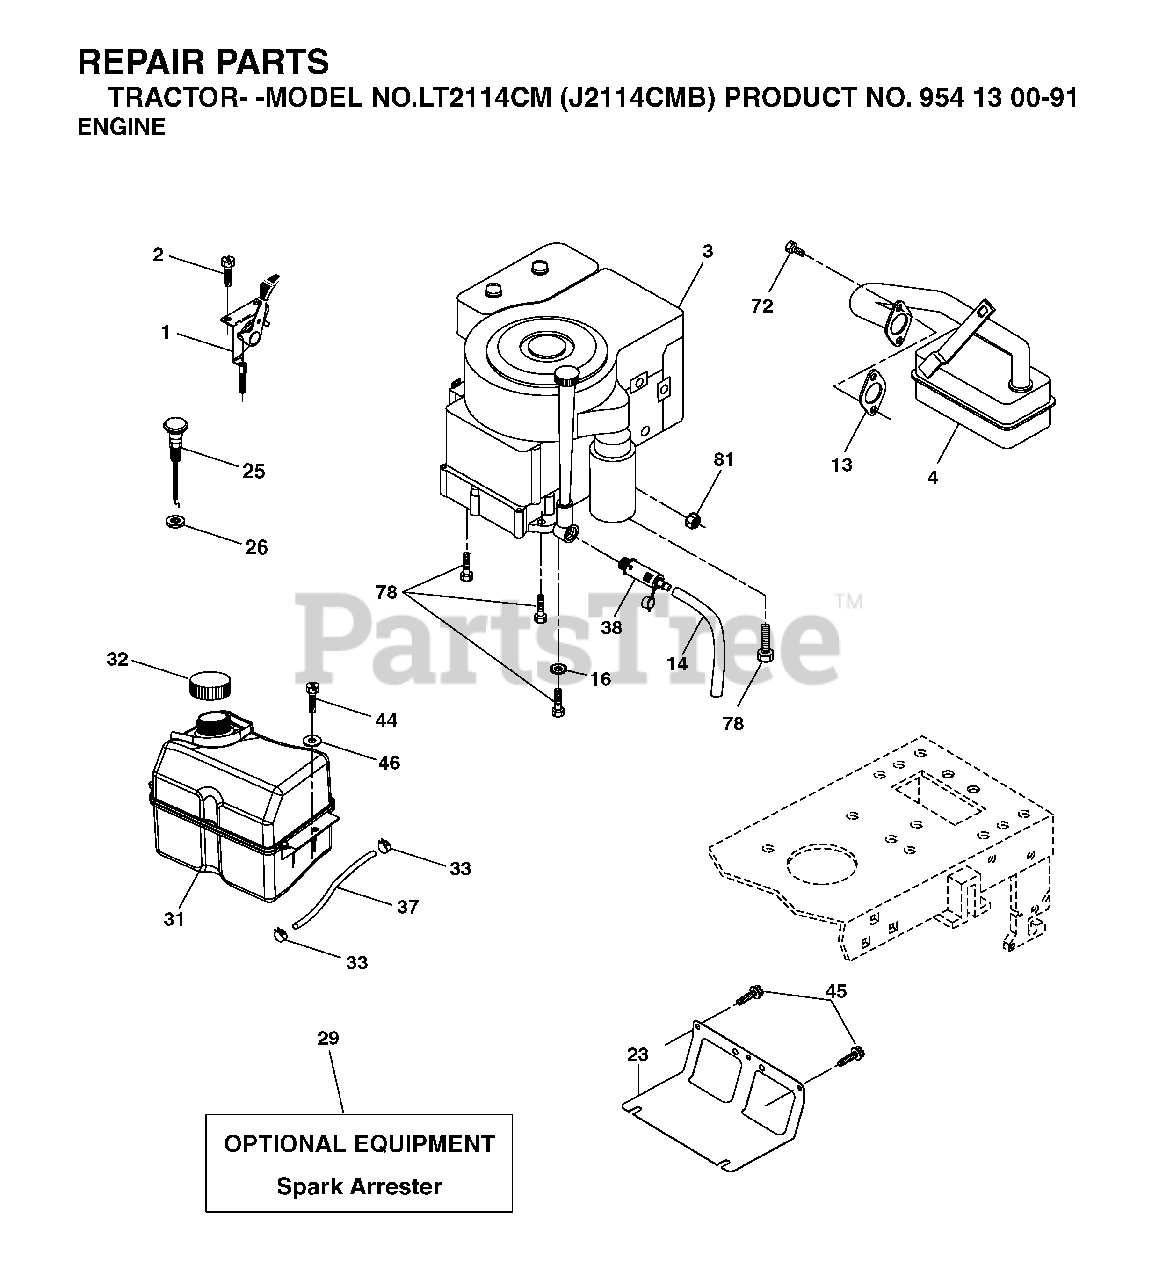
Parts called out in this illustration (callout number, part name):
1	CONTROL TH/CH FLAG
2	SCREW
13	REPL BY 532 27 22-93
14	TUBE, DRAIN OIL ASM.
16	LOCKWASHER
23	SHEILD.BROWNING.DBR.GUARD
26	NUT KEPS 3/8 - 24 UNF
29	ARRESTER SPARK (OPTIONAL)
31	TANK FUEL
32	FUEL CAP
33	HOSE CLAMP
37	LINE.FUEL.20
38	PLUG DRAIN OIL EASY
44	SCREW HEXWSHR 1/4-20X3/4
45	SCREW, 3/8-16X3/4
72	SCREW.SOCKET.HEAD.5/16-18
78	SCREW.3/8-16
81	NUT
